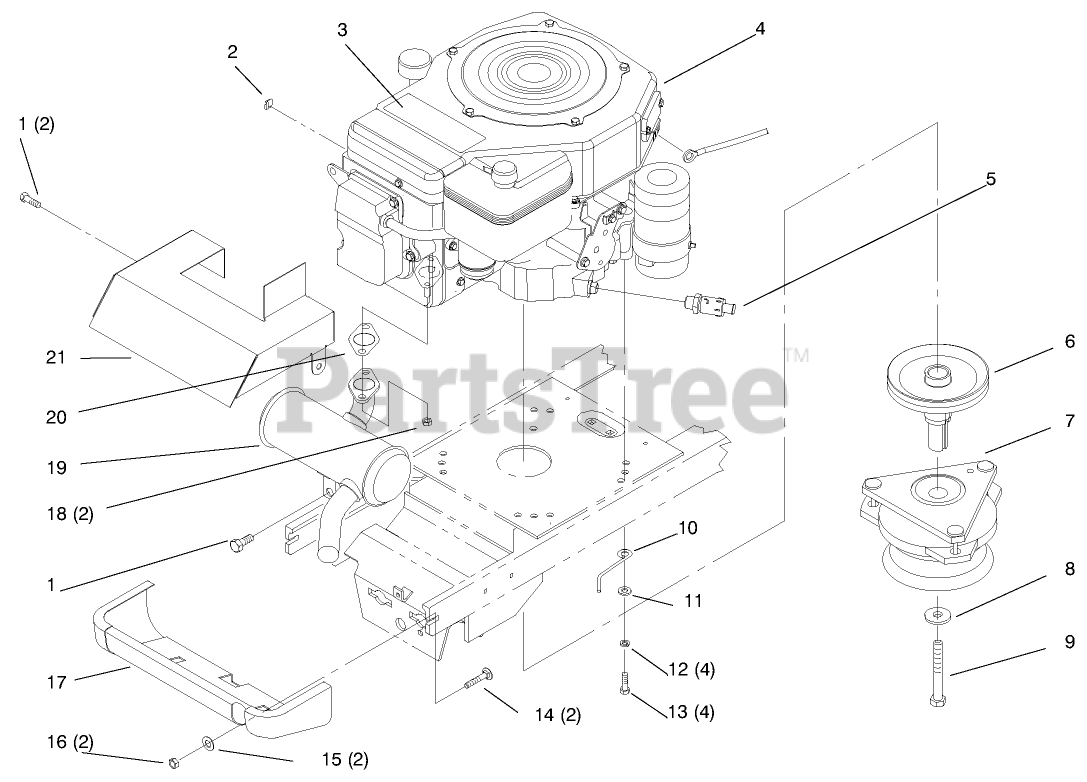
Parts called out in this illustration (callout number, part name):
1	SCREW-HWHTF
2	CLIP-RETAINER, WIRE
4	Engine-Kohler(Only On: 70264)
5	VALVE-DRAIN, OIL
6	PULLEY-ENGINE
7	CLUTCH - ELEC PTO
7	CLUTCH - PTO
8	WASHER
9	SCREW-HH
12	WASHER-LOCK
14	BOLT-CARR
15	WASHER-FLAT
16	NUT-LOCK, NI
19	MUFFLER - SINGLE
20	KOHLER 12-041-03
21	SHIELD-MUFFLER
